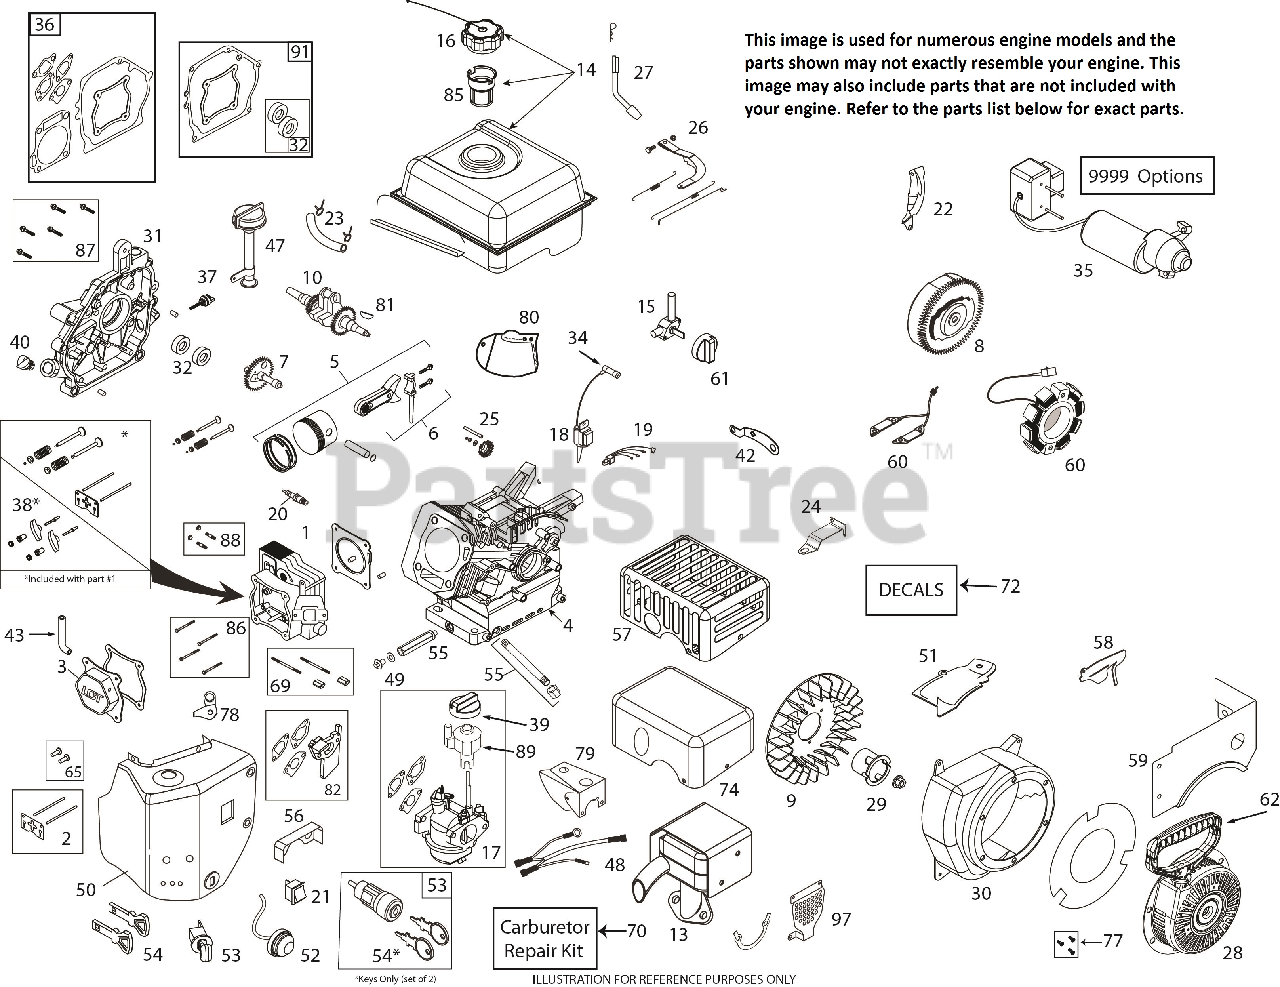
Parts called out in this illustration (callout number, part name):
1	CYLINDER HEAD ASSY(W/GASKET)
2	PUSH ROD & PLATE KIT(W/GASKET)
3	VALVE COVER (W/GASKET )
5	PISTON & ROD ASSEMBLY
7	CAMSHAFT - MCR
8	FLYWHEEL - ELECTRIC START
9	COOLING FAN - FLYWHEEL
10	CRANKSHAFT (#18 KEYED)
13	MUFFLER ASSEMBLY
14	FUEL TANK, MATTE BLACK
15	FUEL TANK ON/OFF VALVE
16	CAP, FUEL TANK (BLACK)
17	CARBURETOR (W/GASKETS)
18	IGNITION COIL (CDI) (STANDARD)
20	SPARK PLUG - PLATINUM
22	SHIELD - FLYWHEEL (ELECTRIC)
23	FUEL HOSE KIT 1/4-230MMW/CLMPS
25	GOVERNOR GEAR ASSEMBLY
26	GOVERNOR ARM & LINK KIT
27	GOVERNOR ARM PADDLE
28	RECOIL STARTER ASSY RND-BLACK
29	STARTER CUP RND STYLE STARTER
30	BLOWER HOUSING (MATTE BLACK)
31	CRANKCASE COVER-HIGH, PRESS IN
32	OIL SEAL KIT(2 PCS 3/4" CRANK)
34	SPARK PLUG BOOT (W/MTL SHIELD)
35	120V ELECT START CONVERSON KIT
36	ENGINE GASKET KIT
38	ROCKER ARM KIT (W/GASKET)
39	CHOKE ON/OFF KNOB (BLACK)
40	NON-REMOVABLE PLASTIC PLUG
43	BREATHER TUBE
47	HIGH OIL-FILL TUBE/DIPSTICK
48	WIRE HARNESS
49	OIL DRAIN PLUG (W/WASHER)
50	HEATER BOX KIT
51	SHIELD - CYLINDER
52	PRIMER BULB WITH HOSE (BLACK)
53	PUSH/PULL KEY & SWITCH (BLACK)
54	PUSH/PULL KEY (BLACK) (PKG OF 2)
55	FRONT OIL DRN PIPE & NUT ASSY
56	CARBURETOR VAPOR SHIELD
57	CE COMPLIANT MUFFLER SHIELD
58	SHIELD - GOVERNOR LINKAGE
59	FUEL TANK SKIRT
60	CHARGING COIL (60-WATT AC)
61	FUEL ON/OFF KNOB (BLACK)
62	STARTER GRIP-SNOW (DELUXE)
65	TAPPET KIT (SET OF 2)
69	CARBURETOR STUDS & COUPLNG KIT
70	CARBURETOR REPAIR KIT
72	SNOW LABEL KIT
74	MUFFLER HEAT SHIELD COVER
77	RECOIL BOLT KIT
79	GOV AND CARB SHIELD, COMPOSITE
81	WOODRUFF FLYWHEEL KEY 5-PACK
82	CARBURETOR SPACER
85	FUEL TANK STRAINER
86	HEAD BLT KIT 136-179-208-254CC
87	CC COVER BLT KIT 179-208-254CC
88	MUFFLER MTG STUD KIT
91	CRANKCASE GASKET KIT 208GEN1&2
97	MUFFLER MANIFOLD SHIELD
9999	CLIPS, CARB THROTTLE LINKAGE
9999	M6X30 ELEC STARTER MNTG BOLTS
9999	STARTER SWITCH SCREWS
9999	HARDWARE KIT (4 M6X10 FLG BLT)
9999	HIGH ALT JET-208CC L10-1 CARB
